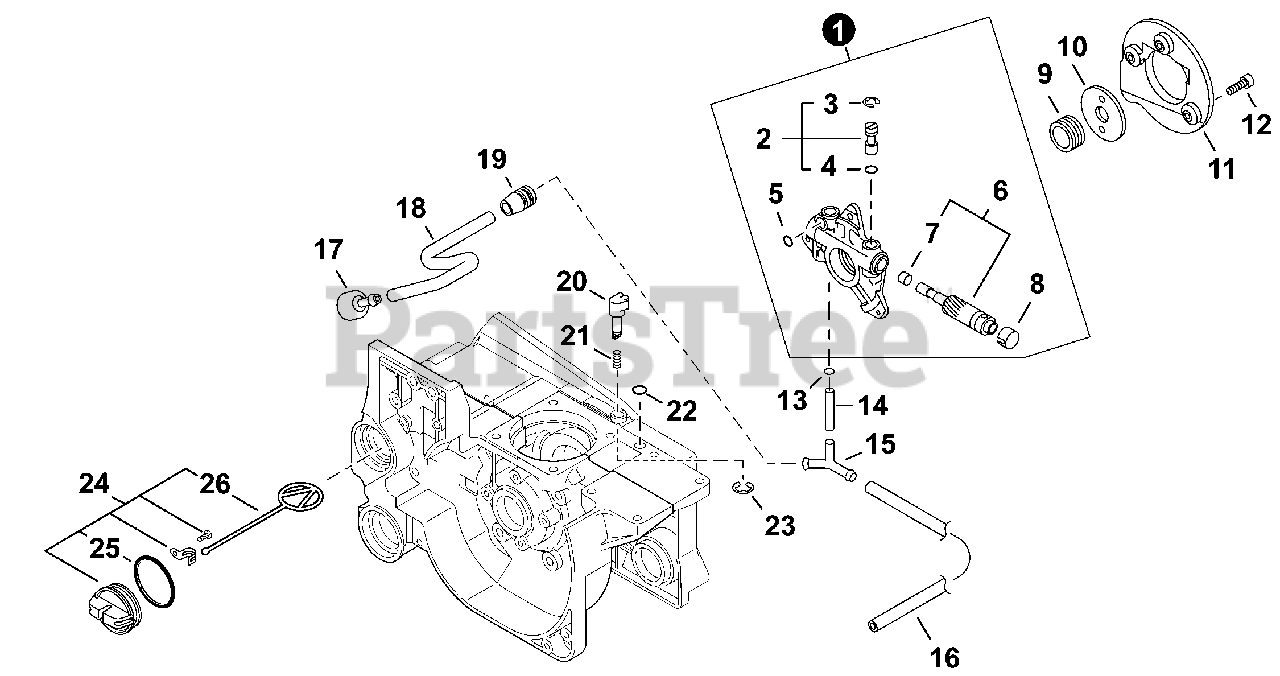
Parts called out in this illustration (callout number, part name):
1	AUTO-OILER ASSY
2	PIN ASSY, CONTROL
5	O-RING 3
6	PLUNGER KIT
8	CAP, PLUNGER
9	GEAR, WORM
11	COVER, OIL PUMP
12	BOLT 4×14
13	CLIP Ø6.5 MM
14	PIPE, OIL 3×6×20
15	CONNECTOR, PIPE
16	PIPE, FUEL 3×6×210 BLACK
17	FILTER, OIL
18	PIPE, OIL
22	O-RING 3
23	E-RING 3
24	CAP ASSY, OIL
26	CONNECTOR, CAP L= 60 MM
